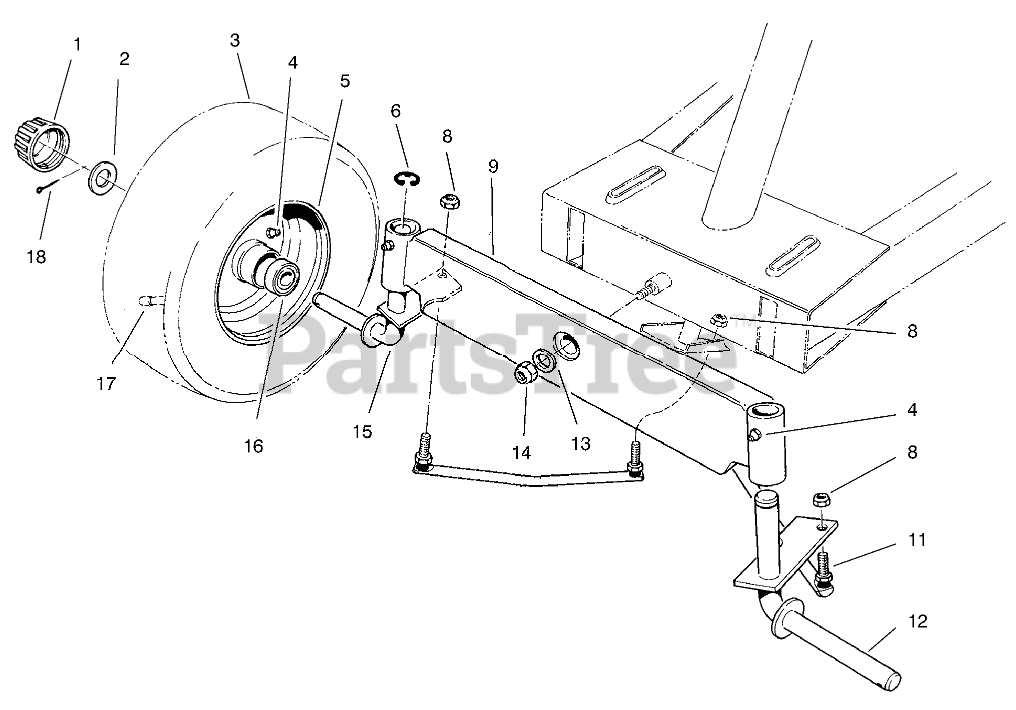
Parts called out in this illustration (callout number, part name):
1	CAP-HUB
2	WASHER-PLAIN
3	TIRE,PNEU.11X4.00X5
4	FITTING-GREASE
6	E-RING
8	NUT-LOCK
9	Axle-Front
11	TIE ROD ASM
12	WHEEL SPDLE WA LH (RED)
13	WASHER-FLAT
14	NUT-LOCK, NI
15	WHEEL SPDLE WA RH (RED)
16	BEARING-WHEEL
17	STEM-VALVE
18	PIN-COTTER
